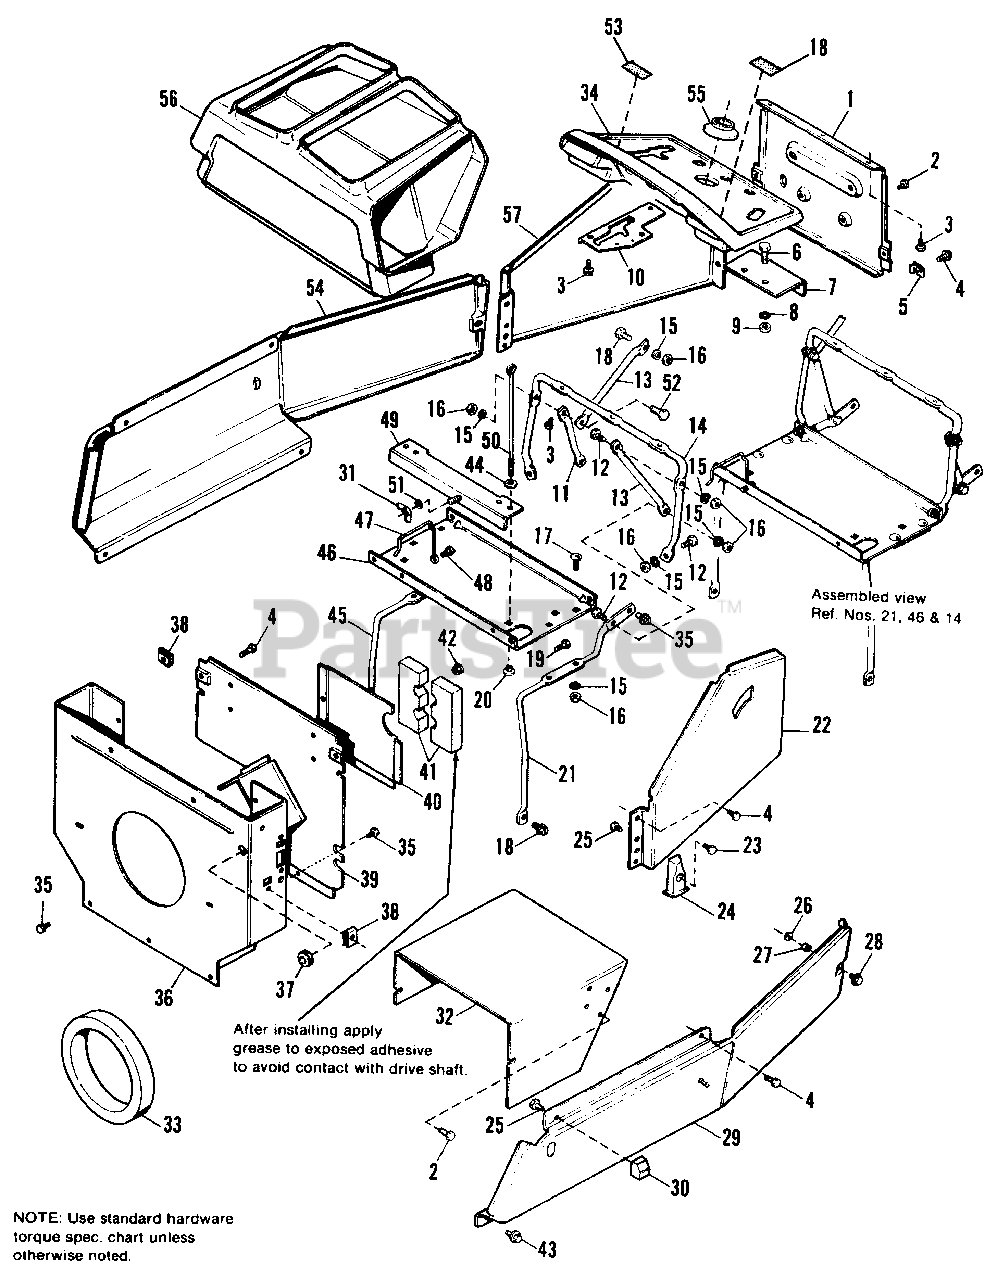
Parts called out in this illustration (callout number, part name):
1	PANEL, Rear Dash
2	SCREW, Hex, Taptite, 1/4-20 x 5/8
3	SCREW, Hex, Plastite, 1/4-10 x 5/8
4	SCREW, Hex, Type "AB", 1/4-14 x 5/8
5	SPEED NUT, "J" Type, 14A
6	CAPSCREW, Hex Hd., 3/8-16 x 1
7	BRACKET, Mounting, Dash Panel, Rear
8	LOCKWASHER, 3/8
9	NUT, Hex, 3/8-16
10	PLATE, Speed Control Lever
11	BRACE, Dash Cap Support, R.H.
12	CAPSCREW, Hex Hd., 5/16-18 x 3/4
13	BRACE, Dash Cap Support, L.H.
14	SUPPORT, Dash Cap
15	LOCKWASHER, 5/16
16	NUT, Hex, 5/16-18
17	BOLT, Carriage, 5/16-18 x 7/8
18	DECAL, Indicator, Left
19	CAPSCREW, Hex Hd., 1/4-20 x 3/4
20	NUT, Plastic, 1/4-20
21	SUPPORT, Battery Tray, L.H.
22	DASH PANEL, Upper, L.H.
23	SCREW, Hex, 1/4 x 1
24	GUIDE, Spacer, Hood
25	SCREW, Hex, Plastite, #10-14 x 1/2
26	PUSHNUT, .250
27	SPACER, Side Panel
28	SCREW, Hex, Taptite, 1/4-20 x 1
29	PANEL ASSY., L.H.
30	SPACER, Hood/Side Panel
31	NUT, Wing, 1/4-20
32	COVER, Tunnel (18 HP only)
32	COVER, Tunnel (20 HP only)
33	SEAL, Engine, Bulkhead
35	SCREW, Hex, Taptite, 5/16-18 x 3/4
37	GROMMET, 1/2" I.D.
38	SPEEDNUT, "U" Type, 14A
39	PANEL ASSY., Bulkhead
40	PANEL, Clean Out
41	SEAL, Drive Shaft
42	NUT, Hex, Flange Whizlock, 1/4-20
43	SCREW, Hex, Taptite, 1/4-20 x 5/8 (Qty. 3 on 20 HP)
44	WASHER, Plain, 1/4 x 5/8 x 3/64
45	SUPPORT, Battery Tray, R.H.
46	TRAY, Battery
47	GUIDE, Plenum
48	SCREW, Hex, Taptite, 1/4-20 x 1/2
49	HOLD DOWN, Battery
50	ROD, Battery Hold Down
51	WASHER, 1/4
52	CAPSCREW, Hex, 5/16-18 x 1-1/4
53	DECAL, Indicator, Right
54	LOWER PANEL ASSY., R.H.
55	BOOT, Steering Stem
56	PLENUM, Air Induction
57	DASH PANEL, Upper, R.H.
